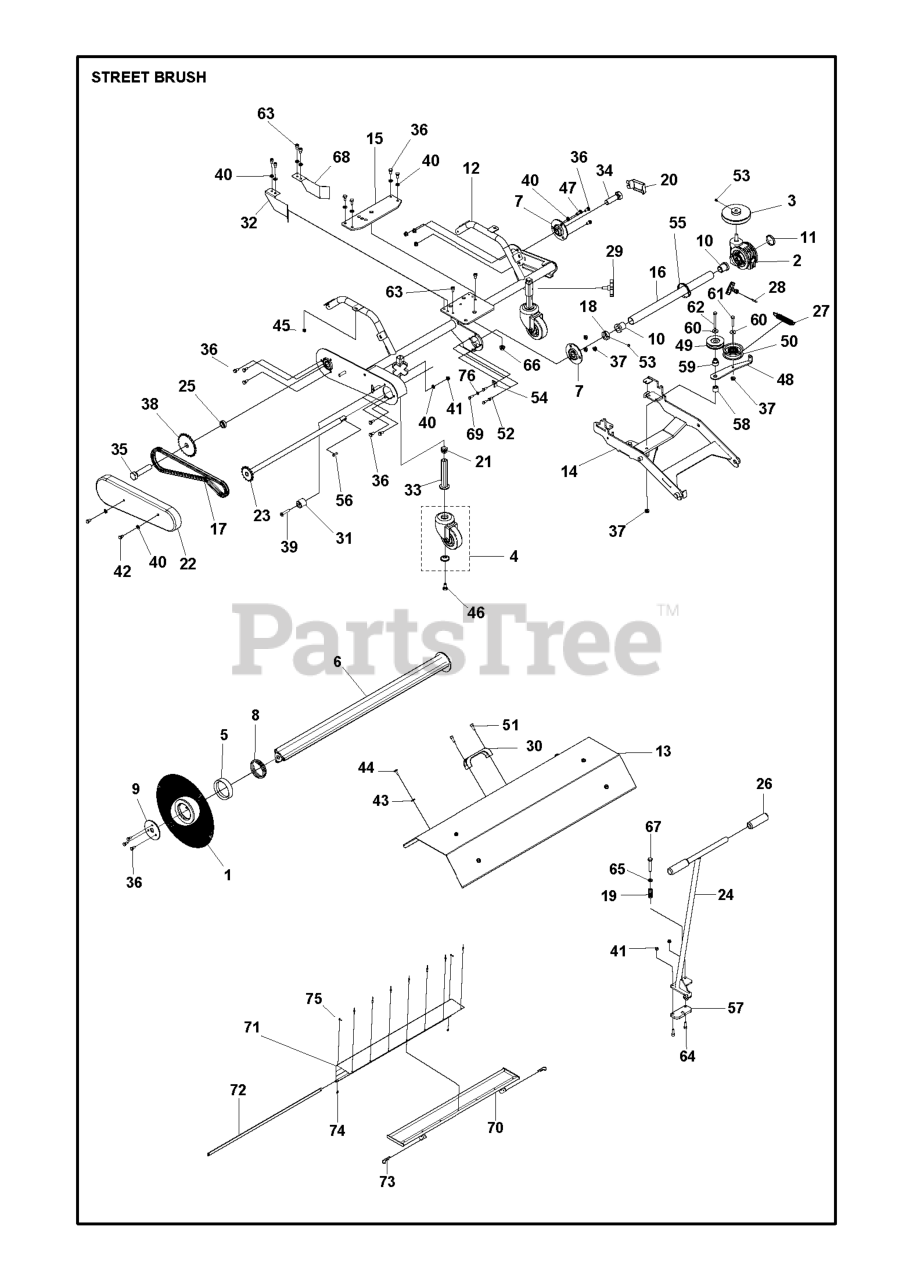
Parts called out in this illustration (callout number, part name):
1	BRUSH RING
4	SUPPORT WHEEL
23	DRIVE SHAFT
31	CHAIN ADJUSTER
37	NUT LOCKING
38	GEAR WHEEL
49	PULLEY ASSY
50	IDLER PULLEY
71	SPRAY GUARD
73	COTTER PIN
